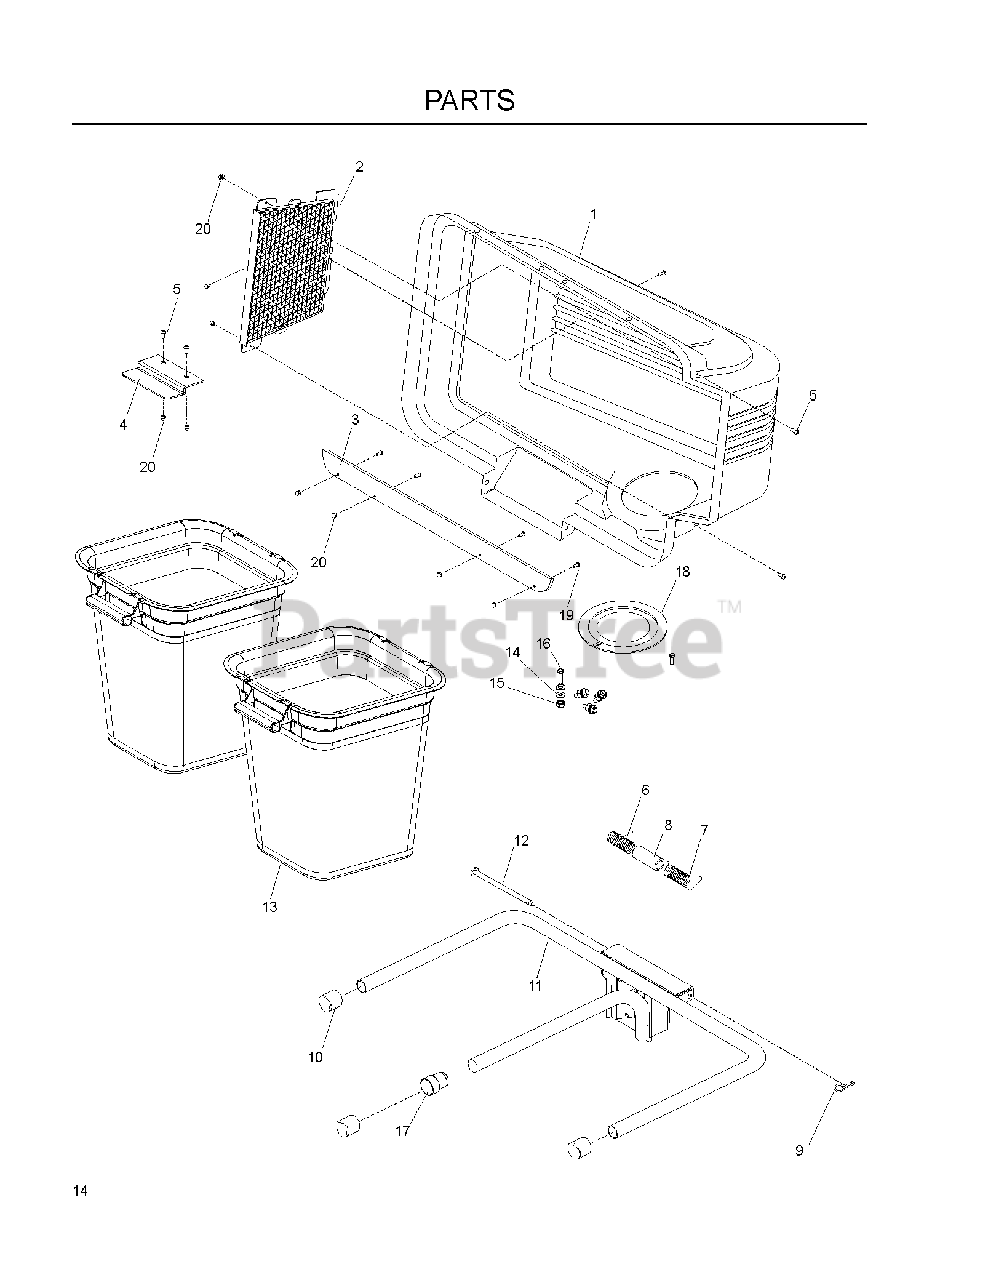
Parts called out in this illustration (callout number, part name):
1	HOOD ASM
2	COVER SCREEN
3	STRIP.REINFORCE.BAGGER.2BIN.BL
4	LATCH CER38
5	SCREW #10-24 X 5/8
6	SPRING COVER LH
7	SPRING COVER RH
8	SPACER.COVER.BAGGER
9	RETAINER SPRING
10	PLUG, TUBING END
11	FRAME.ASM.BAGGER.2BIN.QC42B
12	HINGE PIN
13	CONTAINER BAG, SOFT
14	WASHER #10
15	NUT 10-24 NYLOC
16	SCREW 10-24 X 3/4
17	SPACER PLUG, BAGGER
18	GASKET.COVER.BAGGER
19	SCREW
20	NUT 10-24 ACORN ZD
